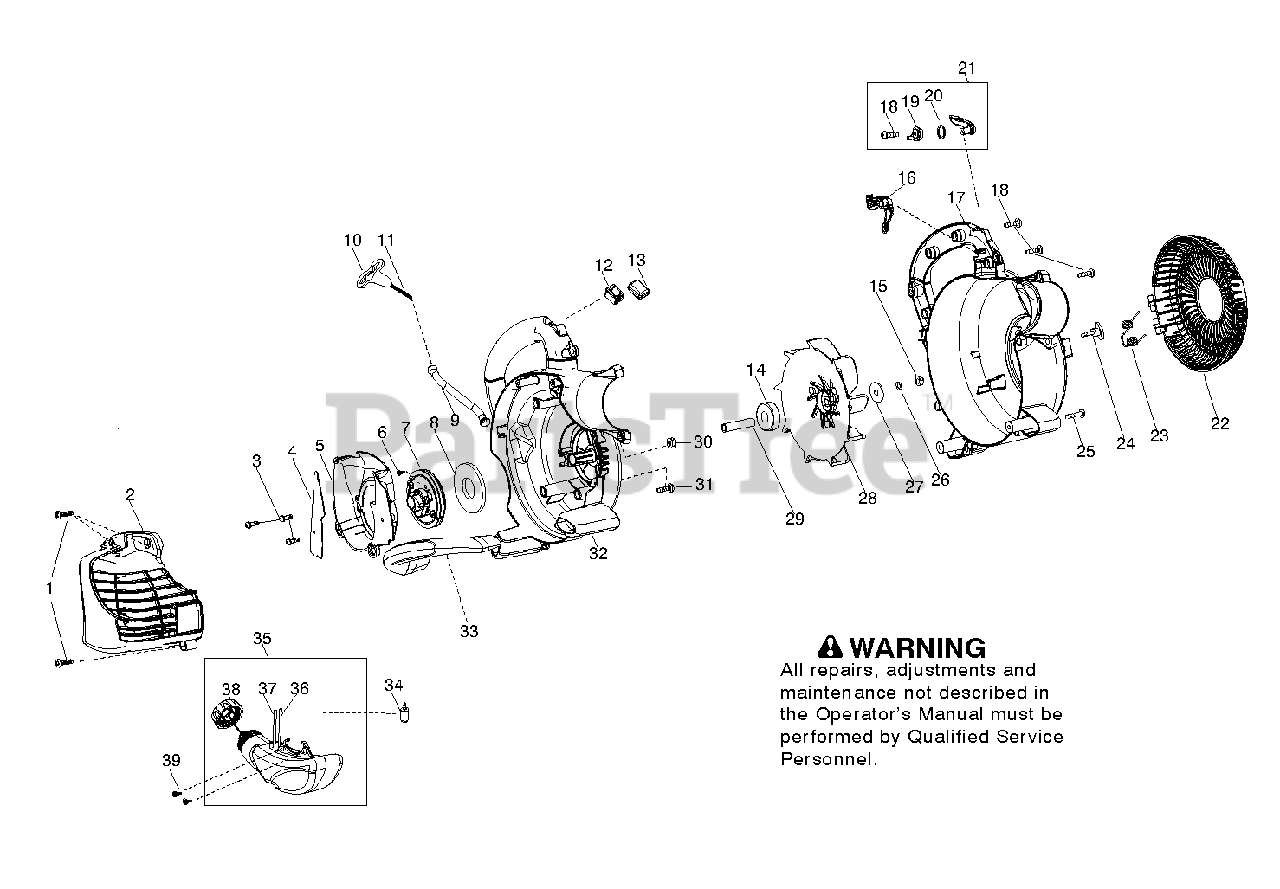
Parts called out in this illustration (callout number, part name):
2	ASSY COVER ENGINE
4	SHIELD BAFFLE
6	SCREW SEMS TOOTHED WASHER
7	KIT STARTER PULLEY
8	KIT STARTER SPRING
9	TUBE STARTER ROPE
10	HANDLE STARTER BLK
11	KIT ROPE
12	KIT SWITCH
13	Protector Switch
14	Hub Bearing
16	TRIGGER THROTTLE SRS RED
17	ASSY SCROLL LEFT PRO GOLD
19	RATCHET CRUISE CONTRO
21	KIT CRUISE CONTROL
22	DOOR VAC BLACK
23	SPRING VAC DOOR
24	KNOB BLOWER
25	SCREW #10 PLASTITE 1.362
26	LOCK WASHER
27	Impeller Washer
28	ASSY IMPELLAR HUB
29	FLYWHEEL SPACER
33	HANDLE VAC BLACK
34	FUEL PICK-UP ASSY
35	FUEL TANK
36	KIT-LINE
37	LINE KIT
38	ASSY FUEL CAP W/RETAINER
39	SCREW FUEL TANK RETAINER
